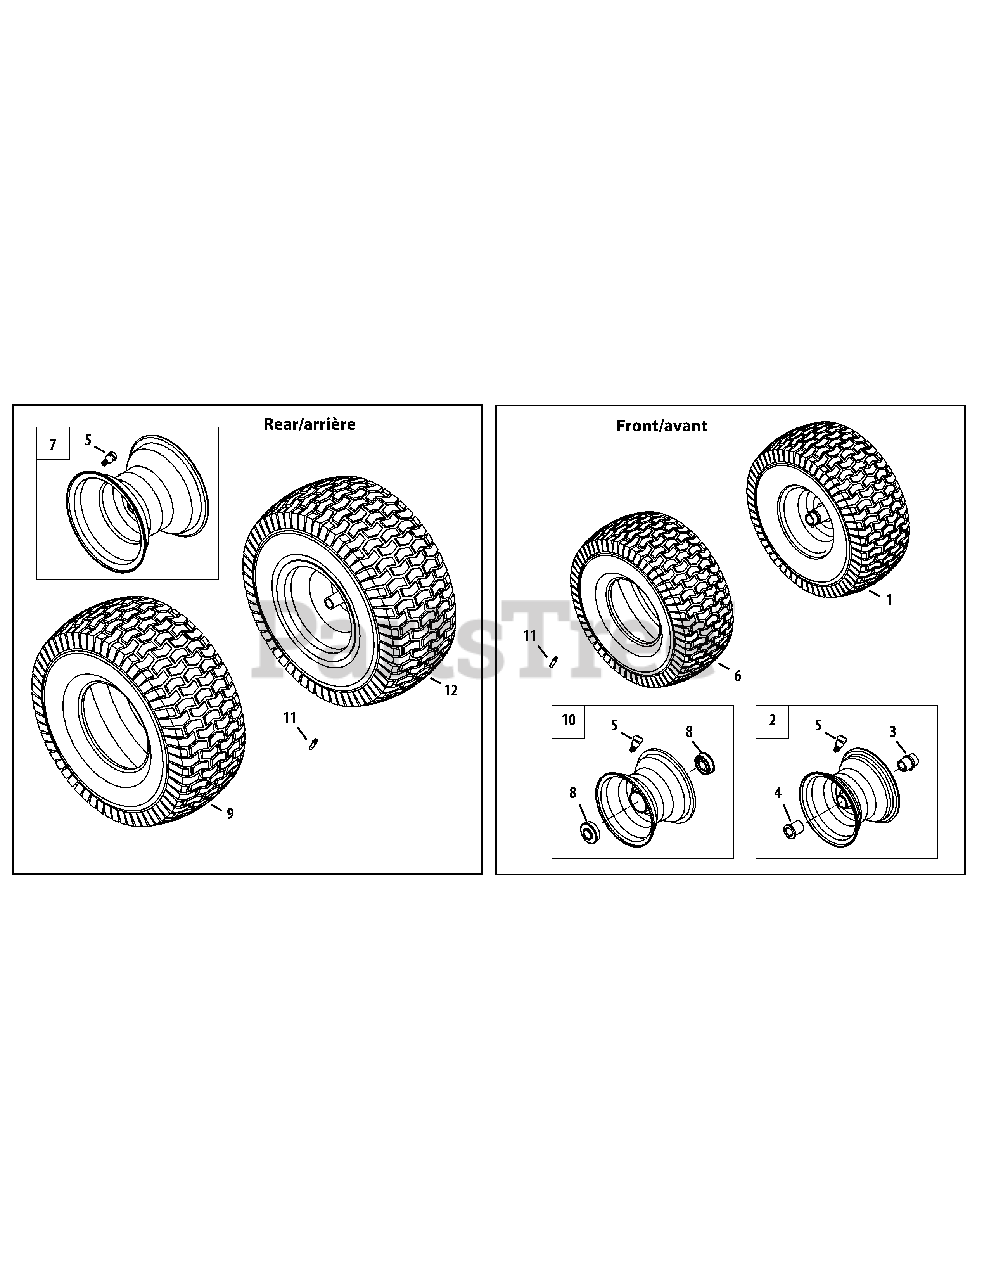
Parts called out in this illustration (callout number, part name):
1	Wheel Ass'y, 16 x 6.5 Ball Brg. (Grey)
5	Air Valve
6	Tire
7	Rim Ass'y, 12.0 x 7.0 (Grey)
8	Ball Bearing .750 ID x 1.750 OD
9	Tire, 23 x 10.5 x 12 Square Shoulder
11	Grease Fitting
12	Wheel Ass'y, 23 x 10.5 x 12 (Grey)
